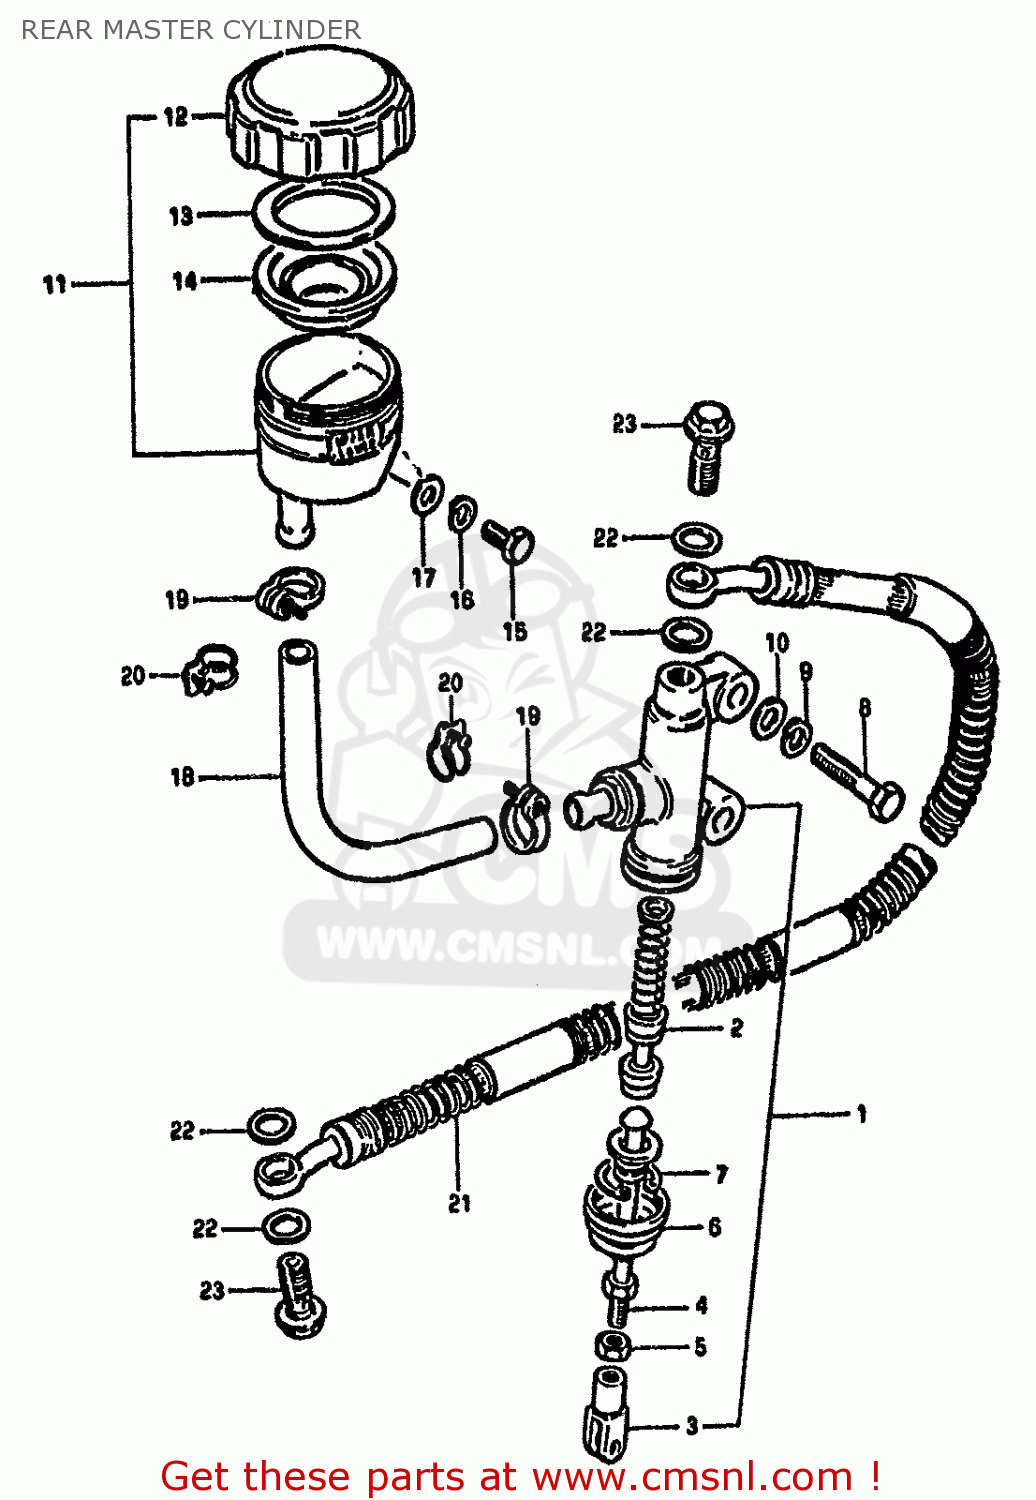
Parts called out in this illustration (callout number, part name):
1	CYLINDER ASSY,RR MASTER
2	PISTON/CUP SET
3	YOKE
4	ROD,REAR MASTER CYLINDER
5	NUT
6	BOOT
7	CIRCLIP
8	BOLT (8X30)
9	LOCK WASHER
10	WASHER
11	TANK ASSEMBLY,RESERVOIR
12	CAP
13	PLATE,DIAPHRAGM
14	DIAPHRAGM
15	BOLT, UPPER
16	LOCK WASHER
17	WASHER
18	HOSE,RESERVOIR TANK
19	CLAMP
20	CLAMP
21	HOSE,REAR BRAKE
22	WASHER
23	BOLT,UNION
